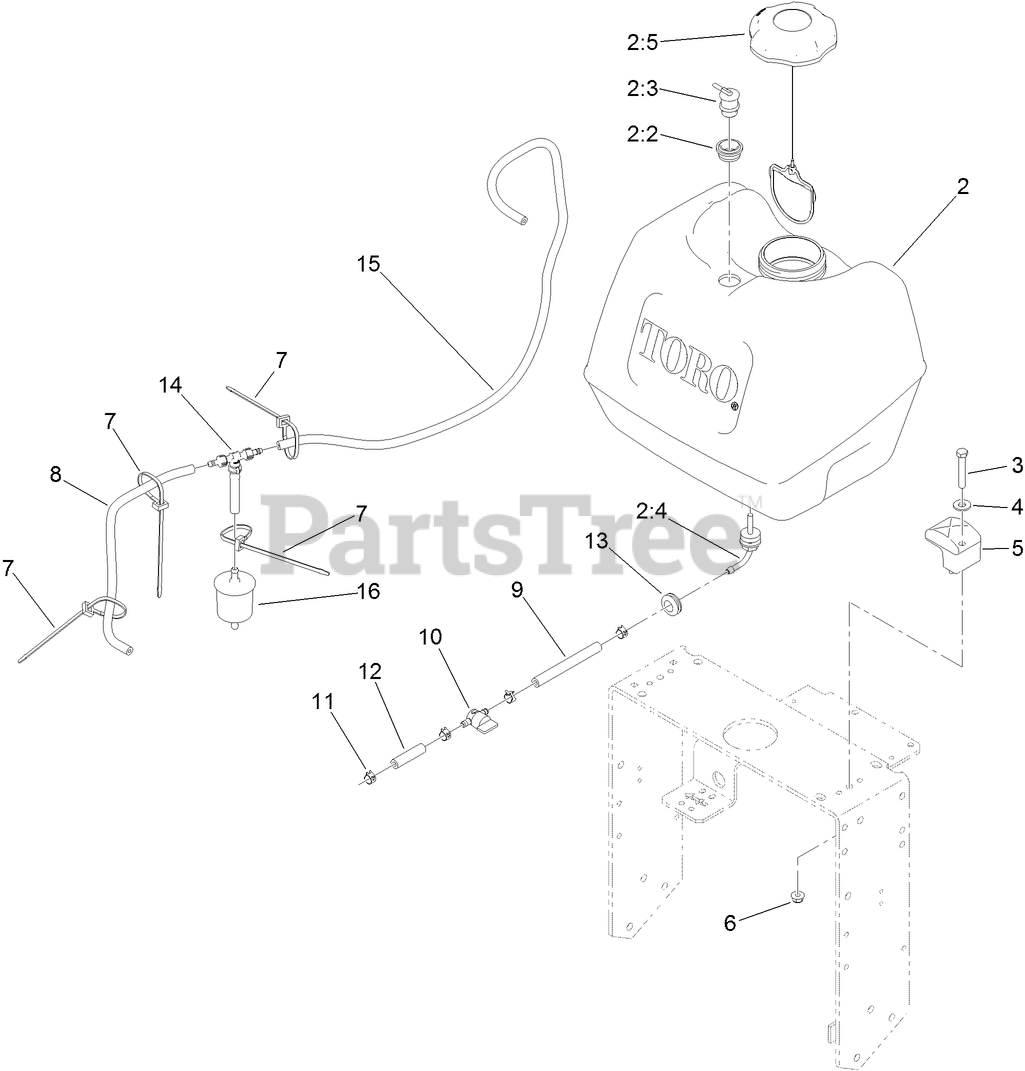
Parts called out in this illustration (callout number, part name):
2	FUEL TANK ASM
2:2	GROMMET
2:3	VALVE-VENT, FUEL
2:4	FITTING-FUEL, BULKHEAD
2:5	CAP-FUEL, RATCHETING
3	SCREW-HH
4	WASHER-FLAT
6	NUT-HF, NI
7	TIE-CABLE
8	HOSE-FUEL
9	HOSE-FUEL
10	VALVE-FUEL
11	CLAMP-HOSE
12	HOSE-FUEL
13	GROMMET
14	TEE AND CHECK
15	HOSE-EMISSIONS
16	FILTER-FUEL
